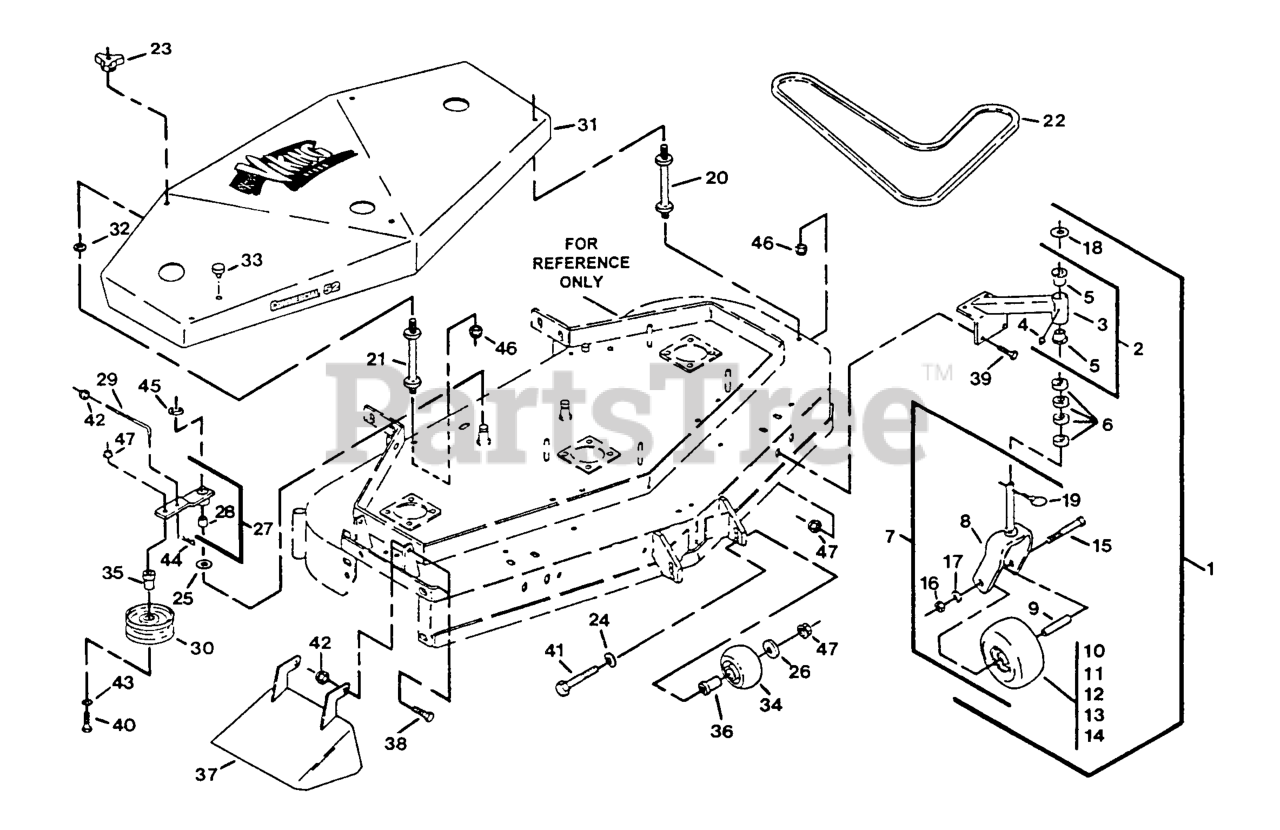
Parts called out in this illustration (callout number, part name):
1	CASTER/MOUNT ASM
2	SUPPORT ASM
5	BEARING-FLANGED
6	SPACER-CASTER
13	BEARING
14	BUSHING
18	WASHER-FLAT
20	STUD-SHIELD, BELT (SHORT)
21	STUD-SHIELD, BELT (LONG)
22	BELT,BLADE DRIVE 48
23	KNOB-3 PRONG
25	WASHER-SPINDLE
27	ARM WLDMNT W/BUSHING
28	BEARING,POWDERED METAL
29	LINKAGE
30	IDLER,PULLEY
31	BELT SHIELD ASSY 52METR
34	ROLLER-SCALP, ANTI
35	BUSHING-IDLER
36	BUSHING-ROLLER
37	WLD,CHUTE DISCHARGE
44	PIN-COTTER
